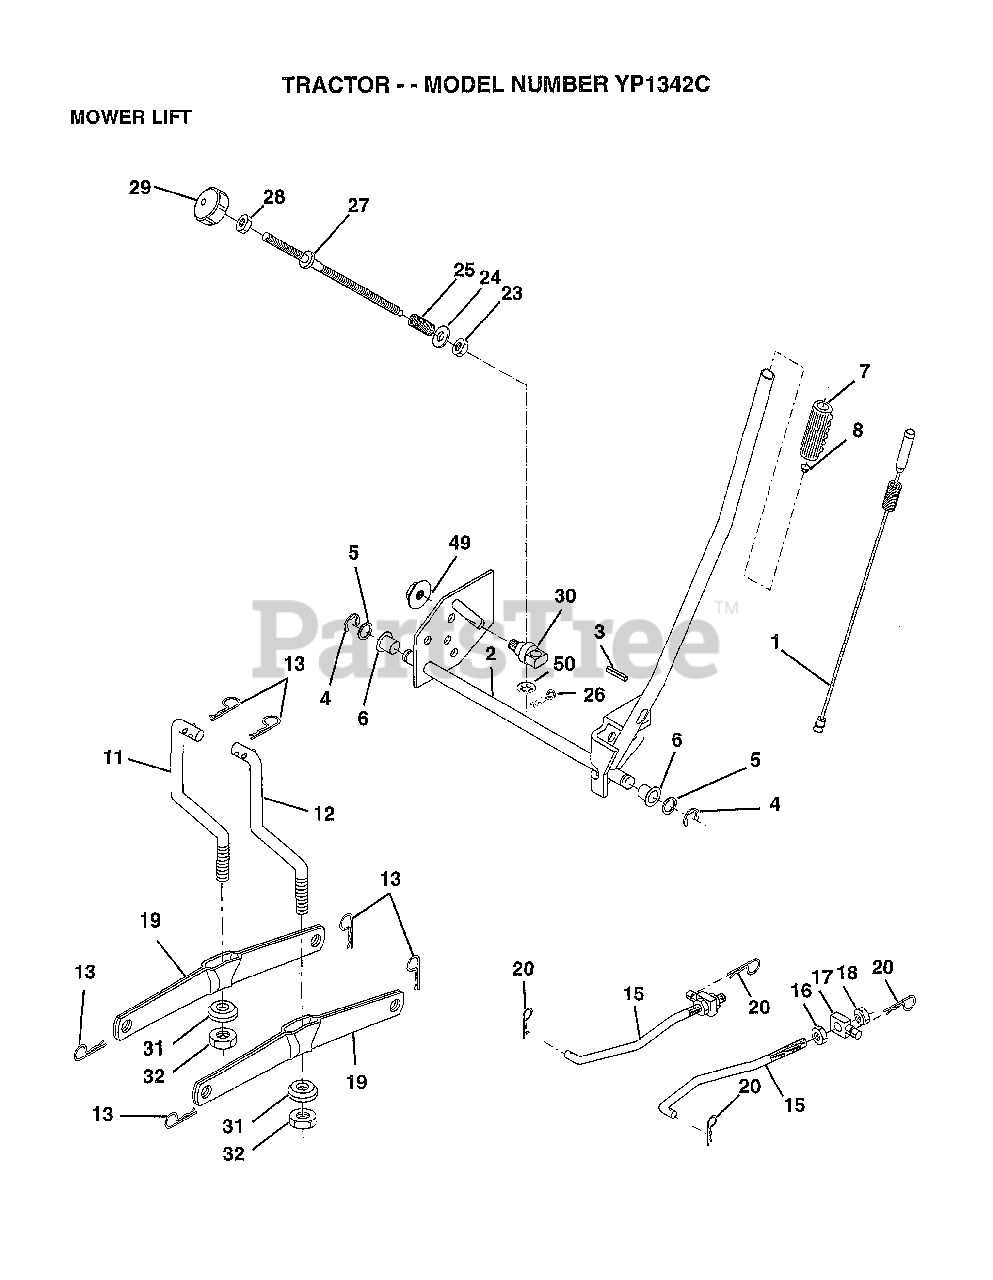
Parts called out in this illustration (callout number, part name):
1	WIRE ASM W.SPRING
2	"SHAFT ASM LIFT,RH"
3	PIN-GROOVE LT
5	WASHER
6	NYLON BEARING
7	GRIP HANDLE
15	LINK.FRONT
16	NUT
17	TRUNION
18	NUT LTV
19	ARM SUSP REAR
20	RETAINER SPRING
23	NUT T
24	WASHER
25	SPRING T
28	NUT
29	KNOB INF 3/8-16
30	TRUNNION
31	BEARING PVT LH
32	NUT.CROWNLOCK.3/8
49	NUT.HXFLG.LOCK.
50	NUT PUSH PHOS. & OIL
